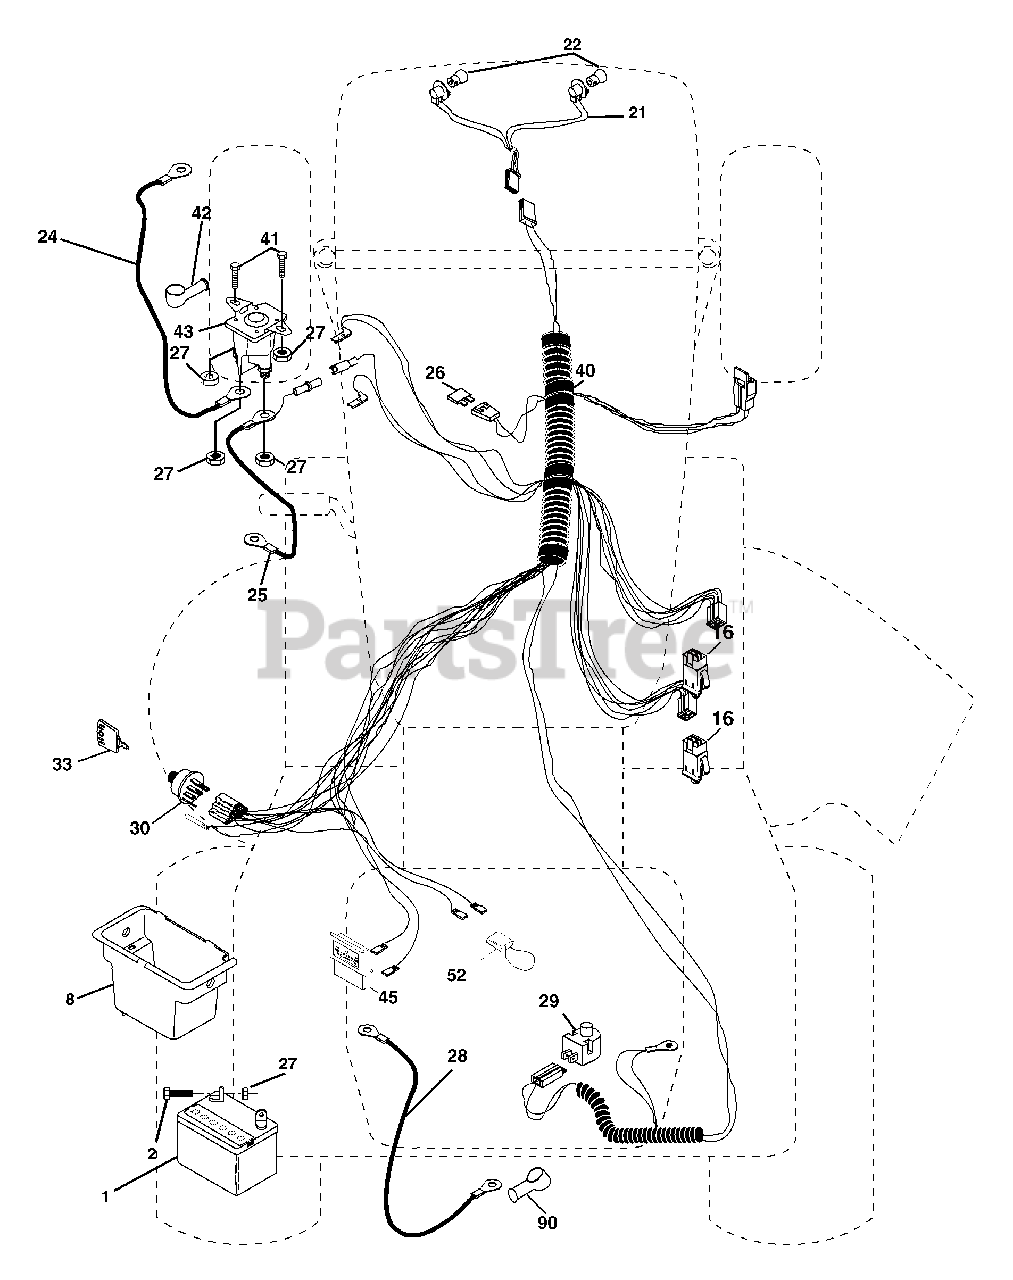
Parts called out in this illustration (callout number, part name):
1	Battery
2	Bolt Hex Hd 1/4-20 Unc x 3/4
8	Box Battery
16	Switch, Interlock
21	Harness Asm Light W/4152j
22	Bulb Light #1156
24	Cable Battery 6 Ga 11" red
25	Cable Battery 6 Ga w/16 wire red
26	Fuse
27	Nut Keps Hex 1/4-20 Unc
28	Cable Ground 6 Ga 12" black
29	Switch Plunger Normal Op Gray
30	Switch Ign
33	Key Ign
40	Harness Ign
41	Bolt Blk. Fin Hex 1/4-20 Unc x 1/2
42	Cover Terminal Red
43	Solenoid
45	Ammeter Rectangular 6 Amp
52	Protection Wire Loop
90	Cover Terminal
